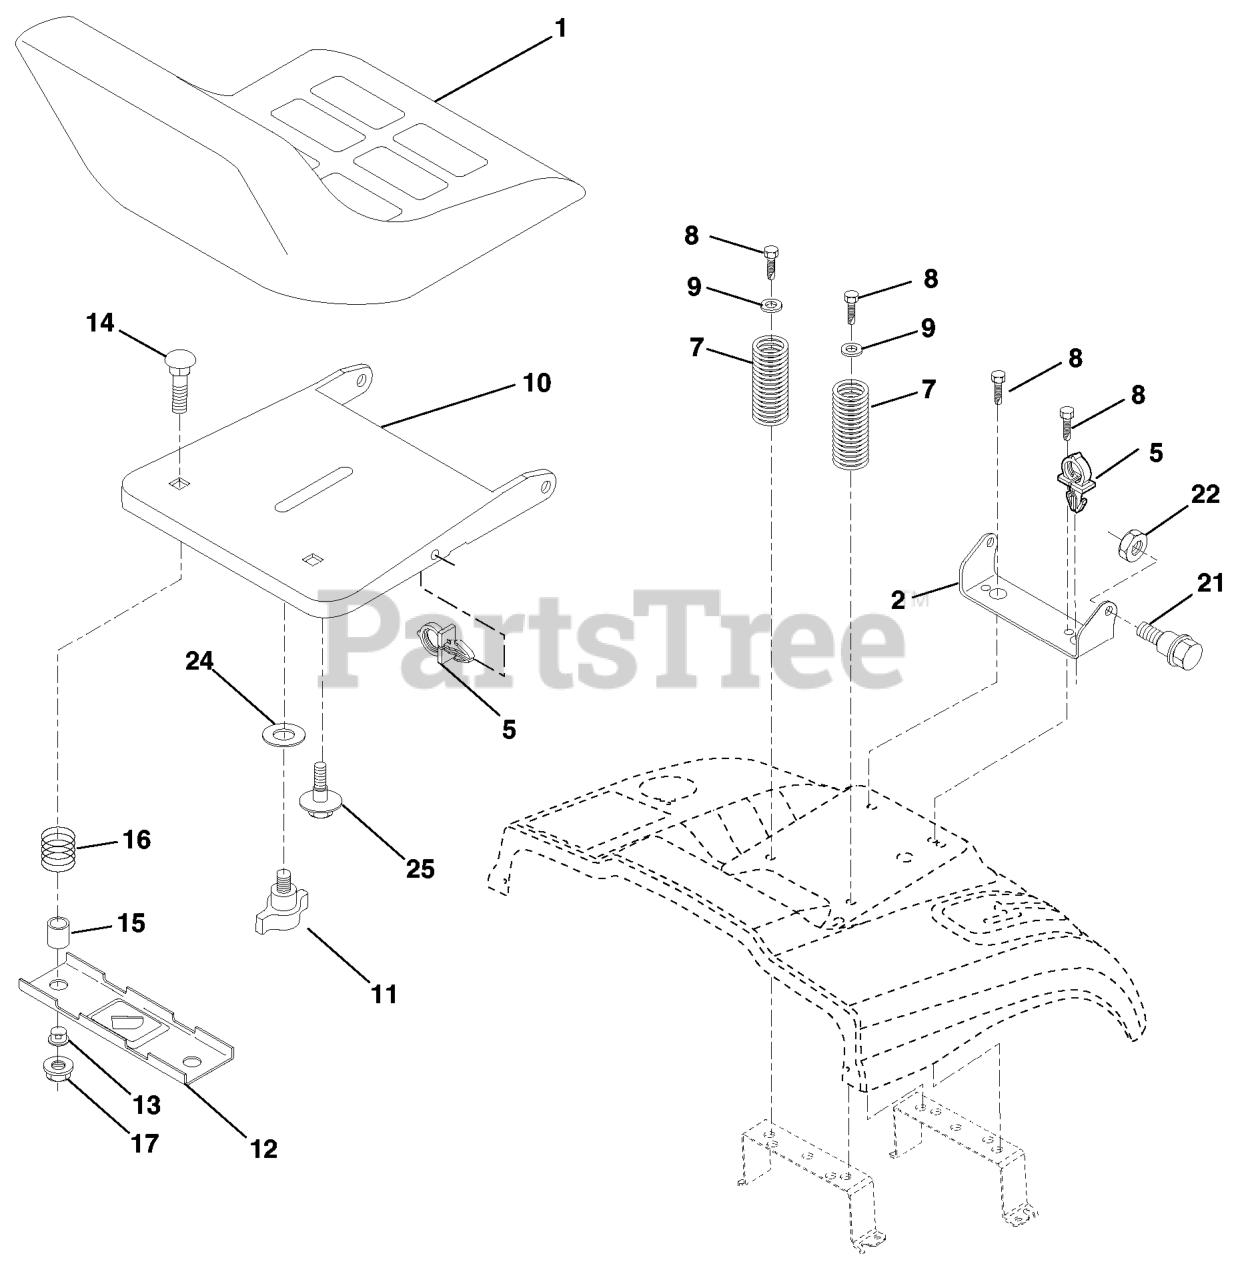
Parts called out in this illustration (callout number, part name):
1	SEAT, GRAY
2	SEAT PIVOT BRKT
7	SPRING COMPRESSION
8	SCREW 3/8-16X1
9	WASHER
10	PAN, SEAT
11	KNOB.SEAT.ADJ.WINGNUT
12	BRKT SWITCH
14	BOLT.ROUND.HEAD.SQUARE.NECK
15	SPACER SPLIT 28X.96
17	NUT T
21	BOLT.SHOULDER.5/16-18
22	NUT.71038.31-18.HEX.NYLOCK
25	BOLT,SHOULD
